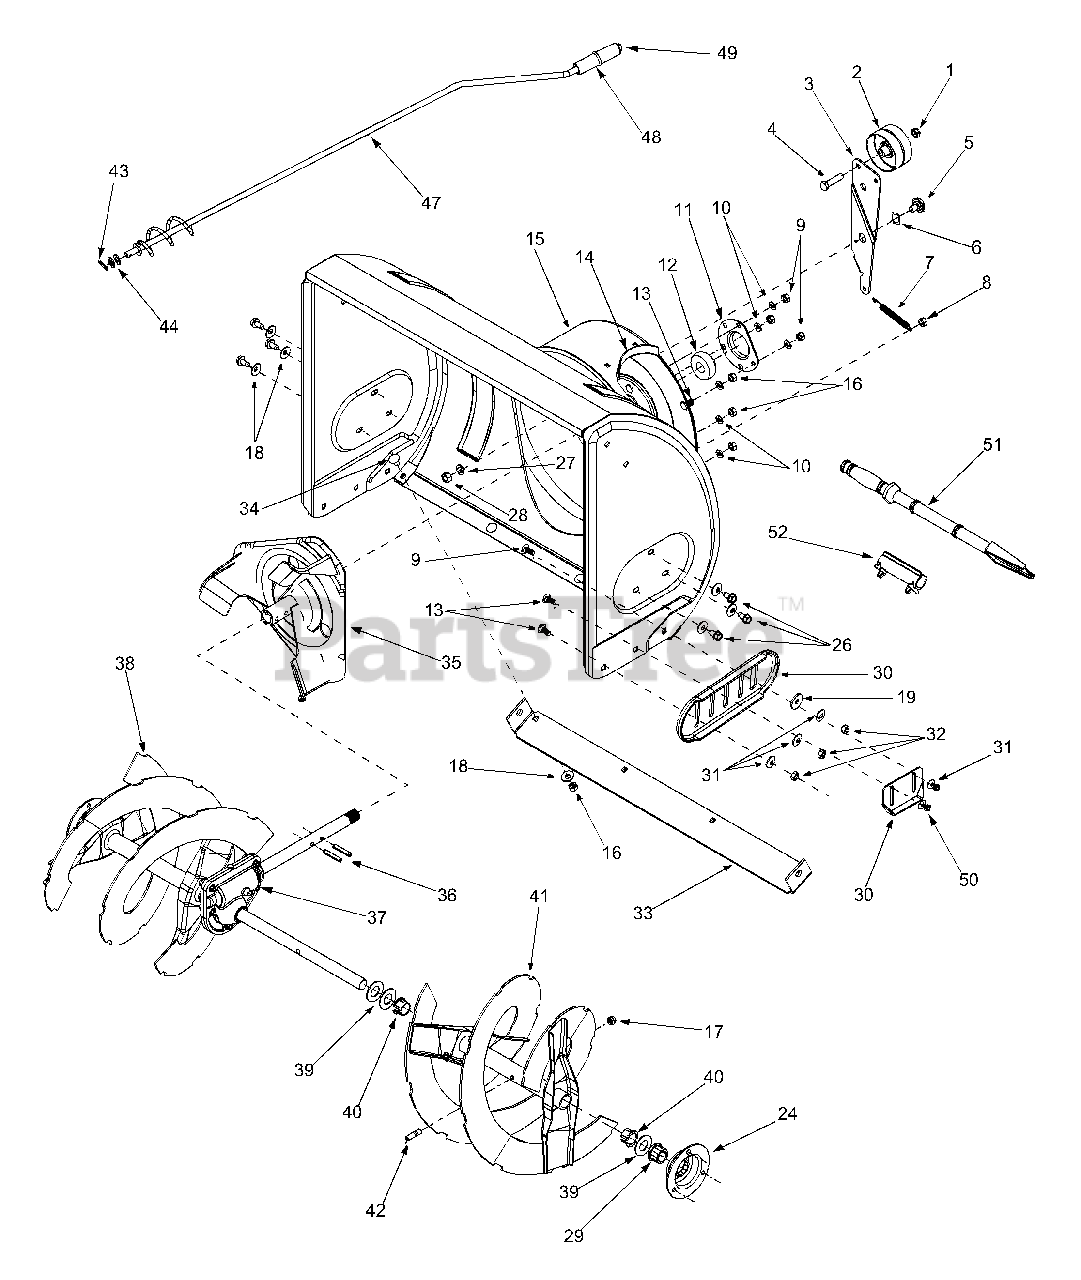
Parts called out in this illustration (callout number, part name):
1	Lock Jam Nut 3/8-24
2	Flat Idler
4	Hex Cap Screw 3/8-24 x 1.50
5	Shoulder Screw
6	Wave Washer
7	Extension Spring
8	Hex Nut 5/16-18
9	Carriage Bolt, 5/16-18 x 1.00
10	Lock Washer 5/16
11	Bearing Housing
12	Ball Bearing
13	Carriage Bolt, 5/16-18 x .75
17	Lock Nut 5/16-18
18	Belleville Washer
19	Flat Wshr, .344ID x 1.125 OD
26	Hex Screw 5/16-18
27	Lock Washer 3/8
28	Hex Nut 3/8-16
29	Hex Flange Bearing
31	Bell Washer
32	Hex Nut 5/16-18
34	Carriage Bolt 5/16-18 x .62
37	28" Gear Ass'y
39	Flat Washer
40	Flange Bushing
42	Shear Bolt 5/16-18 x 1.5
43	Hairpin Clip
44	Flat Washer
47	Chute Crank
48	Chute Crank Knob
49	Push Cap
50	Hex Nut 5/16-18
51	Clean-Out Tool
52	Clean-Out Tool Mount
